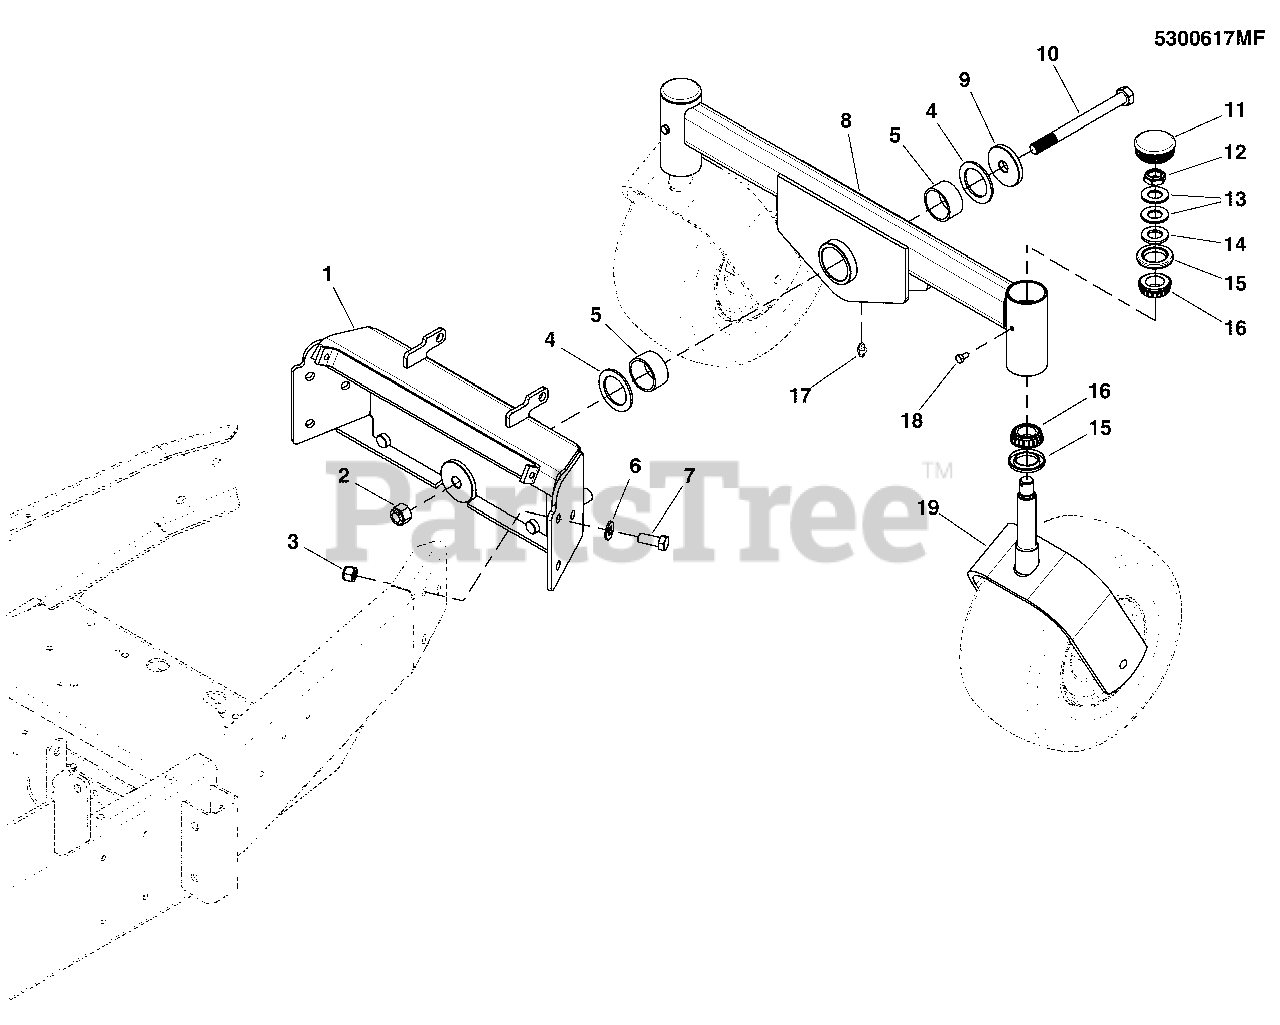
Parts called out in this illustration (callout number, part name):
1	WELD, TAIL WHEEL MOUNT - RED
2	NUT, 5/8-11 HEX NYLON LOCK
3	NUT, 1/2-20 HEX NYLON LOCK
4	THRUST WASHER 1-3/4 X 2-1/2 X 1/8
5	BUSHING, 1-3/4 X 2 X 1
6	WASHER, 1/2 SAE
7	BOLT, 1/2-20 X 1-1/4 GD5 YZ
8	ASSM, TAIL WHEEL MOUNT - S800X
9	WASHER, .656 X 2.44 X .31, YZ
10	BOLT, HEX HD, 5/8-11 X 7 GD5 YZ
11	CAP, LOW PROFILE, STEEL
12	NUT, 3/4-16, HEX JAM NYLON LOCK
13	WASHER, BELLEVILLE - 1.500 X .755
14	WASHER, 3/4 SAE
15	SEAL, GREASE
16	BEARING, TAPERED ROLLER, 1
17	GREASE FITTING, 1/4-28 STRAIGHT
18	BOLT, 1/4-28 X 1/2, GD5 YZ
19	WELD, CASTER YOKE - RED
